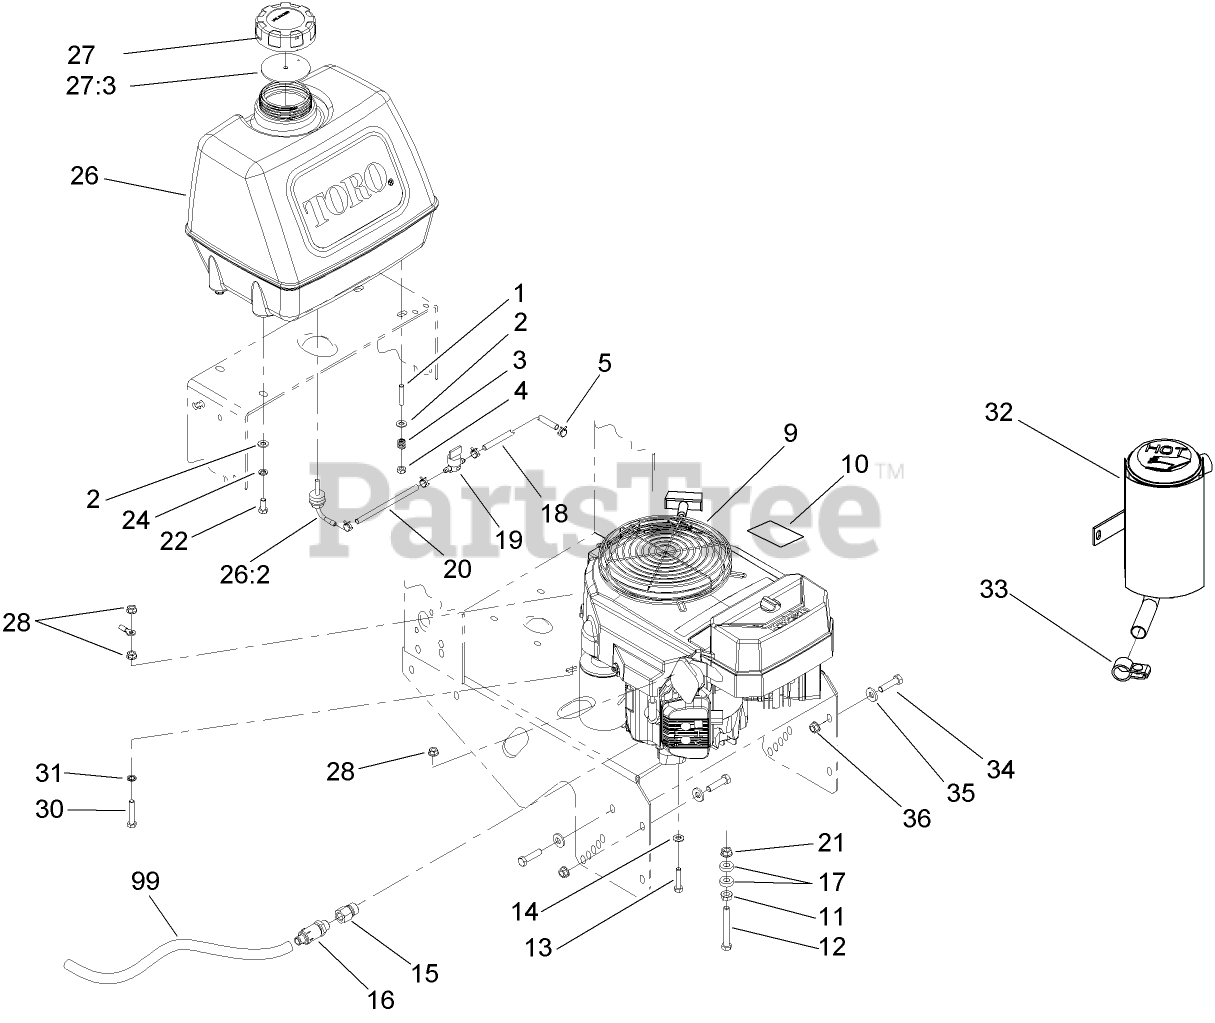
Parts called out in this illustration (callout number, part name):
2	WASHER-PLAIN
3	SPRING-TANK, FUEL
4	NUT-LOCK, NI
10	DECAL-WARNING
11	NUT-HF
12	SCREW-HH
13	SCREW-HH
14	WASHER-SPRING
15	Adapter
16	VALVE-DRAIN, OIL
17	SPACER
18	HOSE-FUEL
19	VALVE-FUEL
20	HOSE-FUEL
21	NUT-LOCK, NI
22	SCREW-HH
24	WASHER-LOCK
26	FUEL TANK ASM
26:2	FITTING-FUEL, BULKHEAD
27	GAS CAP ASM
27:3	GASKET-CAP, GAS
28	NUT-HF
30	SCREW-HH
31	WASHER-LOCK, INTERNAL
32	MUFFLER
33	CLAMP-MUFFLER
34	SCREW-HH
35	WASHER-BELLEVILLE
36	NUT-HHF, WHIZ
99	HOSE-DRAIN, OIL
